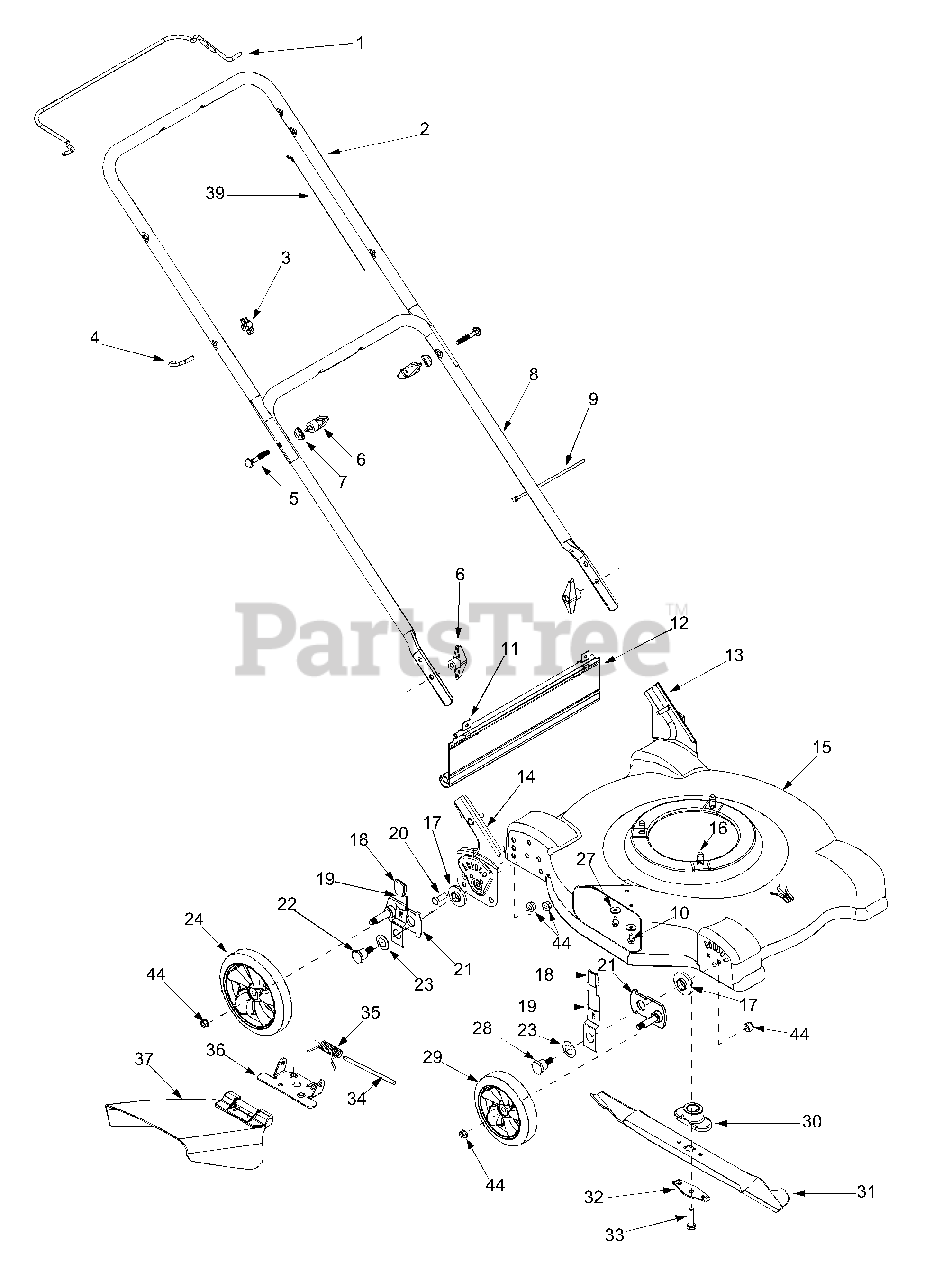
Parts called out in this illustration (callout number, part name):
3	Wing Nut
4	Eye Bolt
5	Carriage Bolt 5/16-18 x 2.0
6	Wing Nut
7	Shoulder Washer.320 ID x.93 OD
9	Cable Tie
10	TT Screw 1/4-20 x 0.5"
11	Hinge Clip
12	Trail Shield
16	TT Screw 3/8-16 x 1.0
17	Height Adjuster Bearing
18	Height Adjuster Knob
19	Lever Assembly
20	Hex Cap Screw 3/8-16 x.75
21	Pivot Arm
22	Shoulder Screw
23	Bell Washer.760 ID x 1.25 OD
24	Rear Wheel 8 x 1.8
27	Bell Washer.265 ID x.75 OD
28	Shoulder Screw
29	Front Wheel 7 x 1.8
30	Blade Adapter
31	Standard Blade 22"
32	Blade Bell Support
33	Hex Cap Screw 3/8-24 x 1.5
34	Hinge Pin
35	Torsion Spring
36	Deflector Chute Adapter
37	Hinged Chute Deflector
39	Blade Control Cable - 37.25" Lg.
44	Lock Nut 3/8-16
